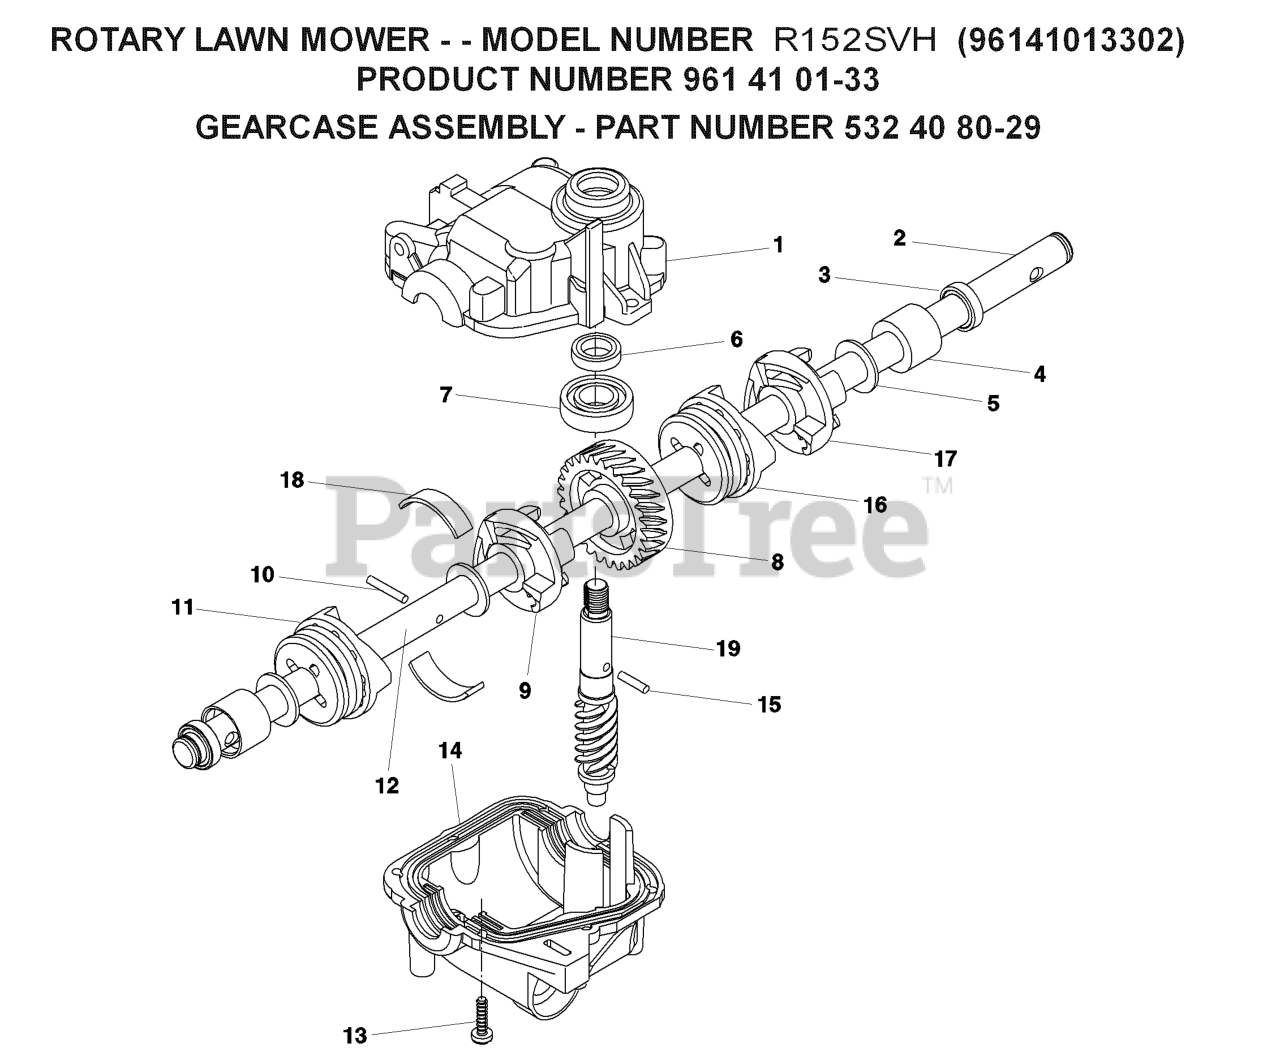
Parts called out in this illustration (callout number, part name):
1	CASE UPPER
3	SEAL.OUTPUT.SHAFT
6	SEAL INPUT SHAFT
8	GEAR 28 TEETH
9	DOG.MOVEABLE.LH.32005
10	PIN 3.50.337 - 33733
11	DOG.FIXED.LH.32003
14	CASE, LOWER
15	PIN 7 33732
16	DOG.MOVEABLE.RH.32006
17	DOG.FIXED.RH.32004
18	SPRING LEAF
